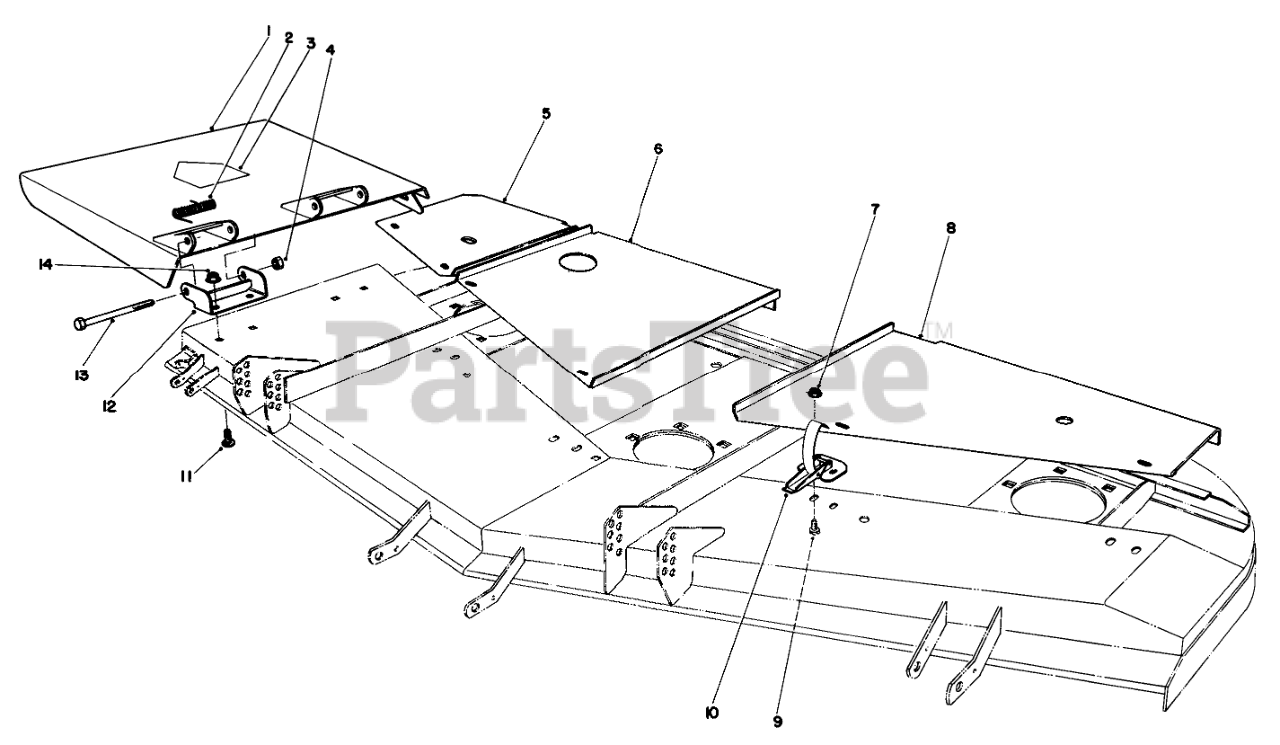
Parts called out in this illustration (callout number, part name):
1	Deflector Assembly (Incl. Ref. #3)
2	SPRING
3	DECAL-DANGER
4	NUT-HEX
5	Cover R.H.
6	Cover-Center
7	NUT-LOCK, FLANGE
8	Cover L.H
9	SCREW-HWH
10	CLAMP-SLOTTED
11	SCREW-CARR
12	Bracket-Hinge
13	SCREW-HH
14	NUT-HHF, WHIZ
